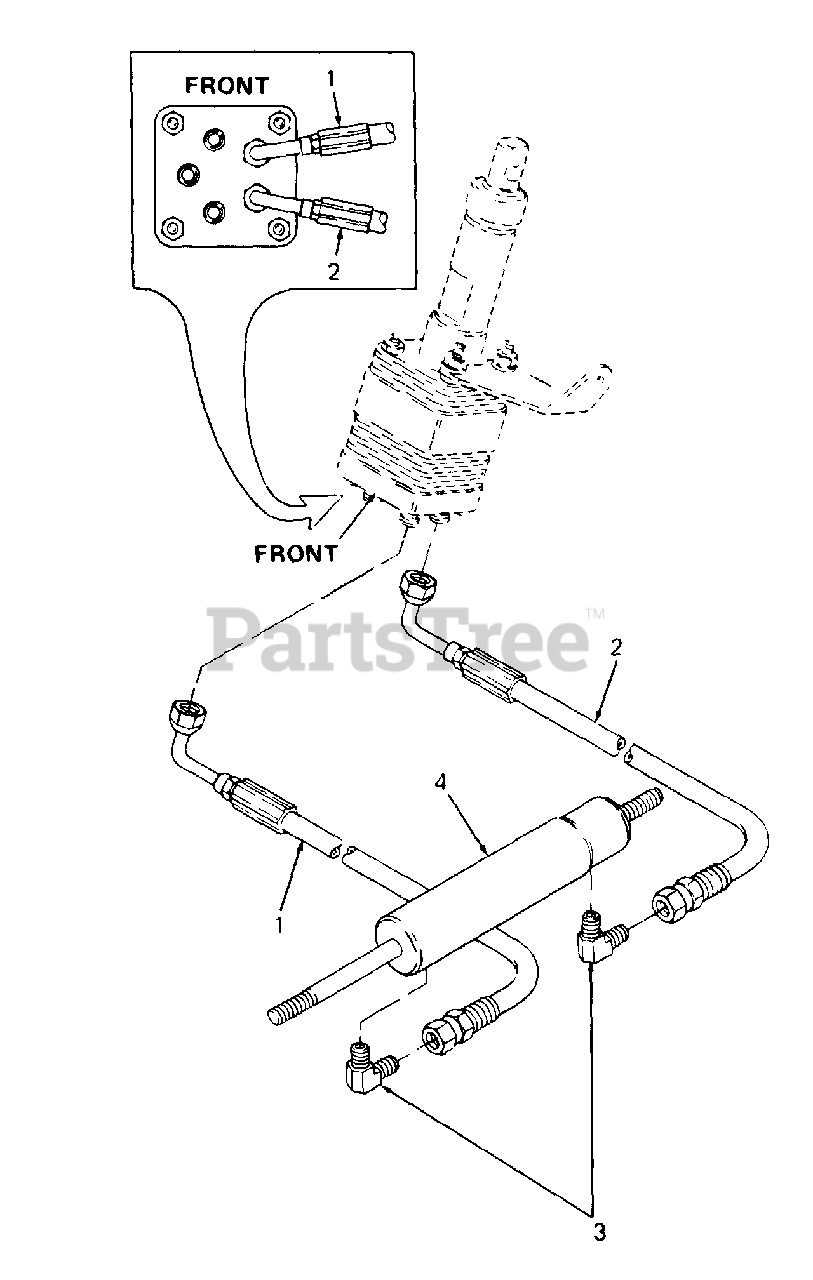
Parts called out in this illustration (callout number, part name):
1	Hose, Steering, 14 Lg
2	Hose, Steering, 11 Lg
3	Elbow, 90 Deg Tube
